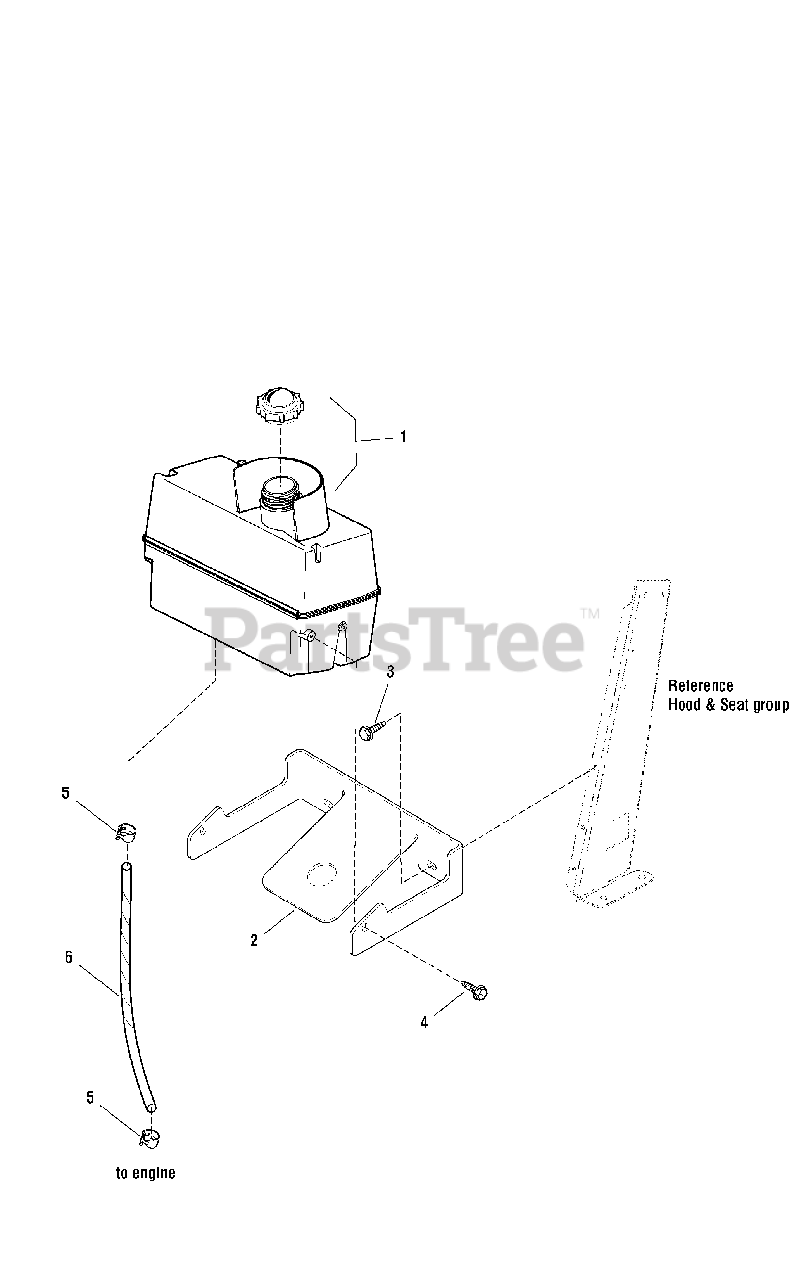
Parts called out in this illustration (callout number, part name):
1	FUEL TANK, w/ Cap
2	BRACKET, Tank
3	SCREW, 1/4-20 x 1/2
4	SCREW, Self Tap, 1/4-20 X 5/8
5	HOSE CLAMP
6	HOSE, Fuel, Low Perm 17 in
